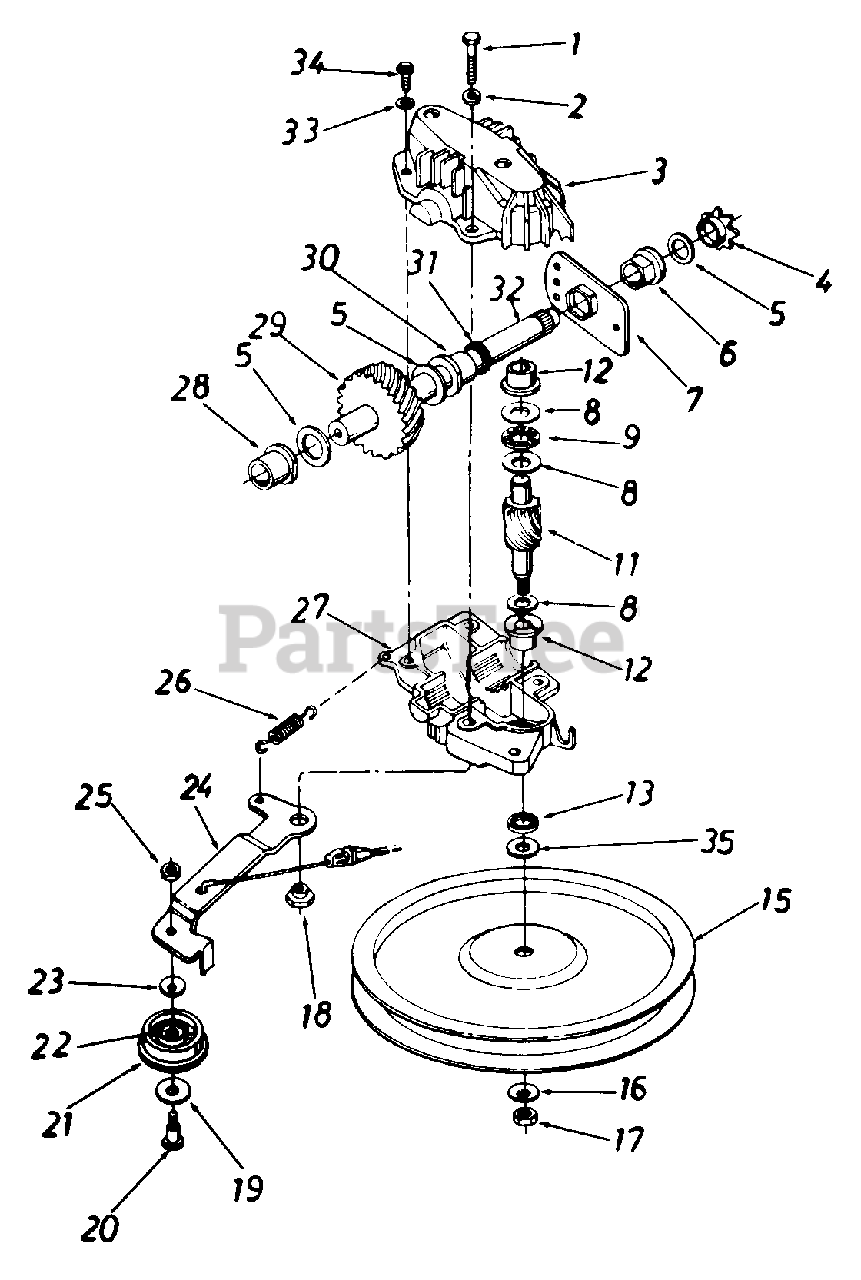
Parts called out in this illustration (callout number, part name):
1	Hex Bolt 1/4-20 x 1.25" Lg. w/Patch
2	L-Wash. 1/4" I.D.
3	Upper Hsg. Half
4	#48 Sprocket 7 Tooth x 1/2 Pitch
5	Fl-Wash. 5/8" I.D. x .030
6	Hex Flange Brg. .631" I.D.
8	Thrust Wash. .382" I.D. x .70" O.D.
9	Thrust Bearing .375" I.D. x .812" O.D.
11	11 Tooth Pinion Shaft
12	Flange Bearing
13	Oil Seal
15	Fl-Pulley 5.06" O.D.
16	Bell-Wash. .265" I.D. x 75"
17	Hex L-Nut 1/4-28 L.H. Thd.
18	Shld. Spacer .375" Dia. x .170
19	Fl-Wash. .390" I.D. x 1.0"
20	Shld. Bolt .375" Dia. x .40"
21	Fl-Idler Plastic 1.50" Dia
22	Needle Brg. .375" x .31
23	Bell-Wash. .265" I.D. x 75"
24	Idler Brk't. Assy.
25	Hex Patch L-Nut 1/4-28 Thd
26	Extension Spring 1.12" Lg.
27	Lower Hsg. Half
28	Flange Bearing .566 Dia.
29	33 Tooth Helical Gear
30	Flange Bearing .629 Dia.
31	Oil Seal .625 Dia.
32	Gear Sprocket Shaft
33	L-Wash. #10 I.D.
34	Hex B-Tap Scr. #10 x .62"
35	Hex Washer .26" x .88"
